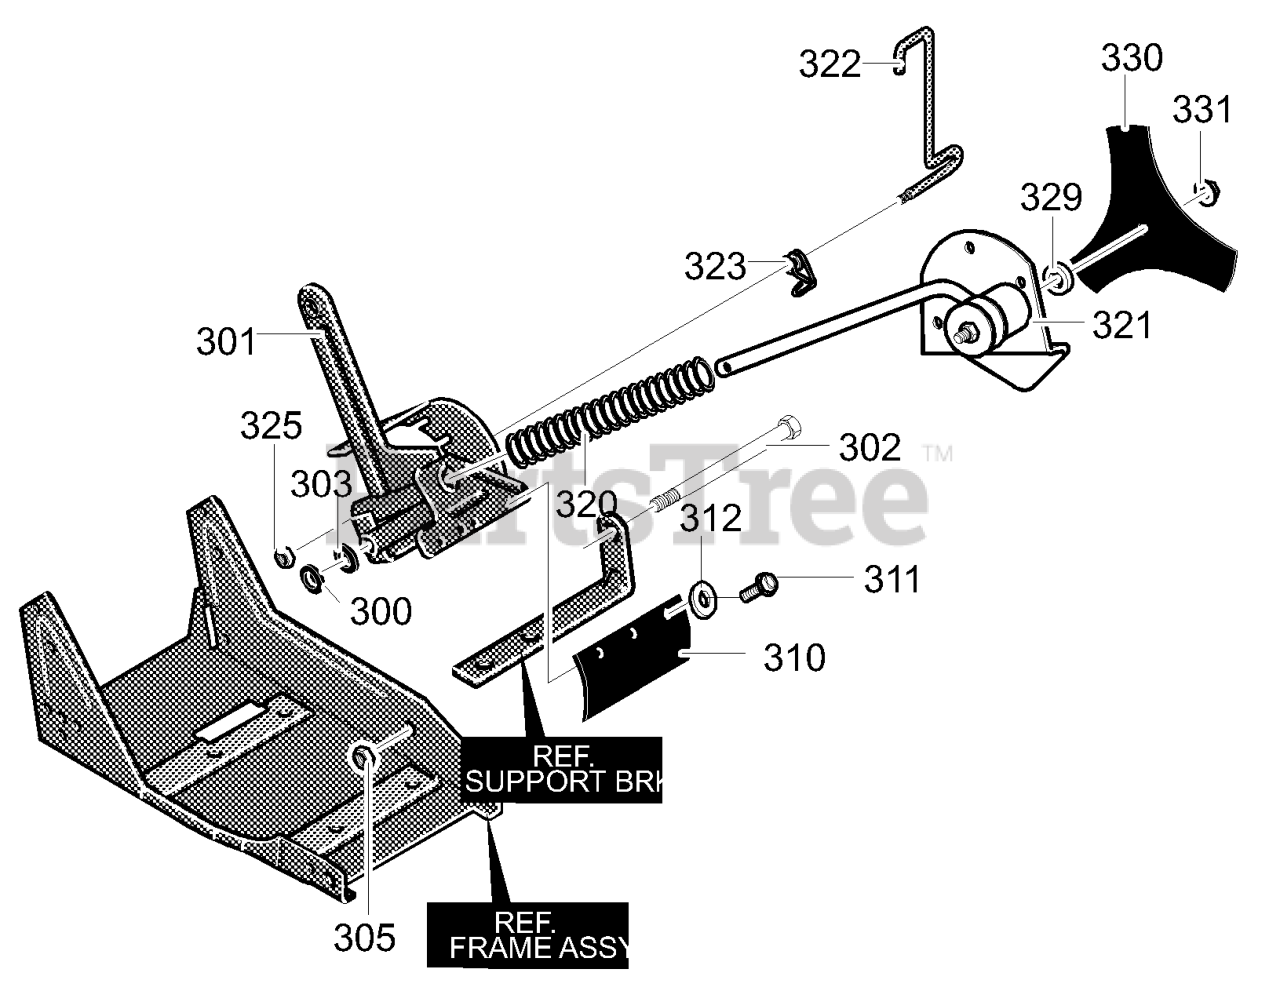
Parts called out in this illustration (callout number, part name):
300	Flatwasher
301	Quill Support
302	Bolt, 3/8-16 HHSH
303	Flatwasher
305	Nut, 3/8-16
310	Rubber Deflector
311	Screw, 10-16x1.50
312	Flatwasher
321	Quill Assembly
322	Lever, Index
323	Spring, Torsion
325	Nut, 5/16-18
329	Flatwasher
330	Blade, Edger
331	Nut, 1/2-20 Wdfl
